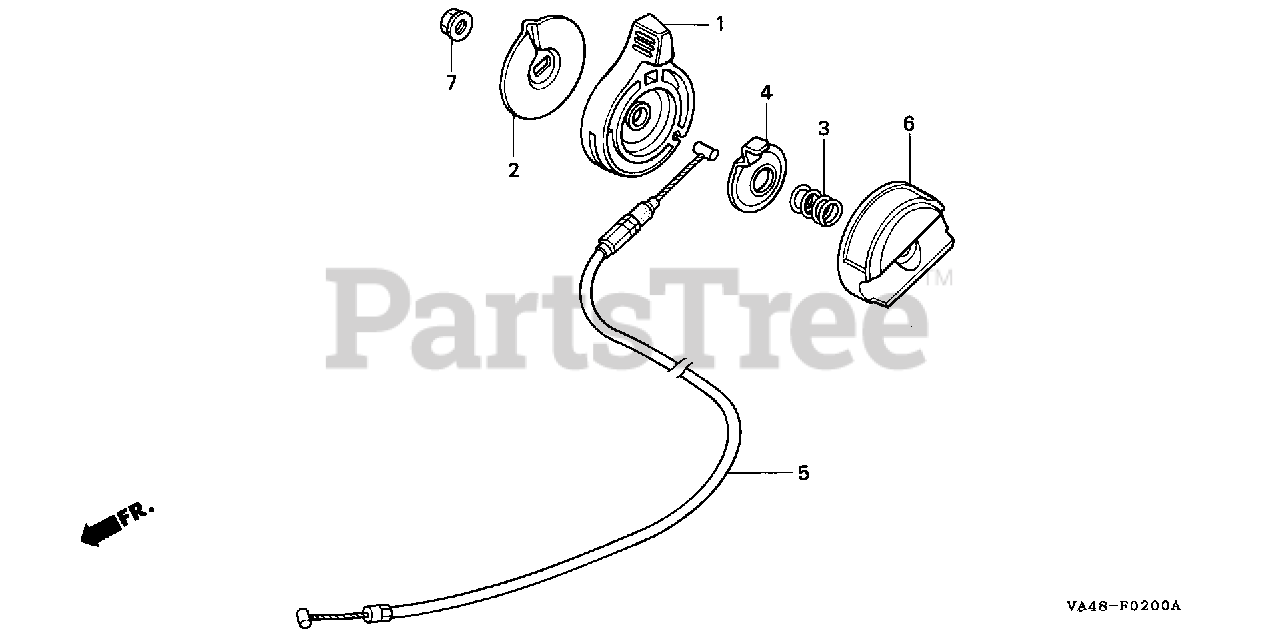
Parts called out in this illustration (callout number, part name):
1	LEVER, THROTTLE
2	PLATE, THROTTLE LEVER
3	SPRING, THROTTLE LEVER
4	SEAT, SPRING
5	CABLE, THROTTLE
6	COVER, CONTROL
7	NUT, FLANGE (6MM)
